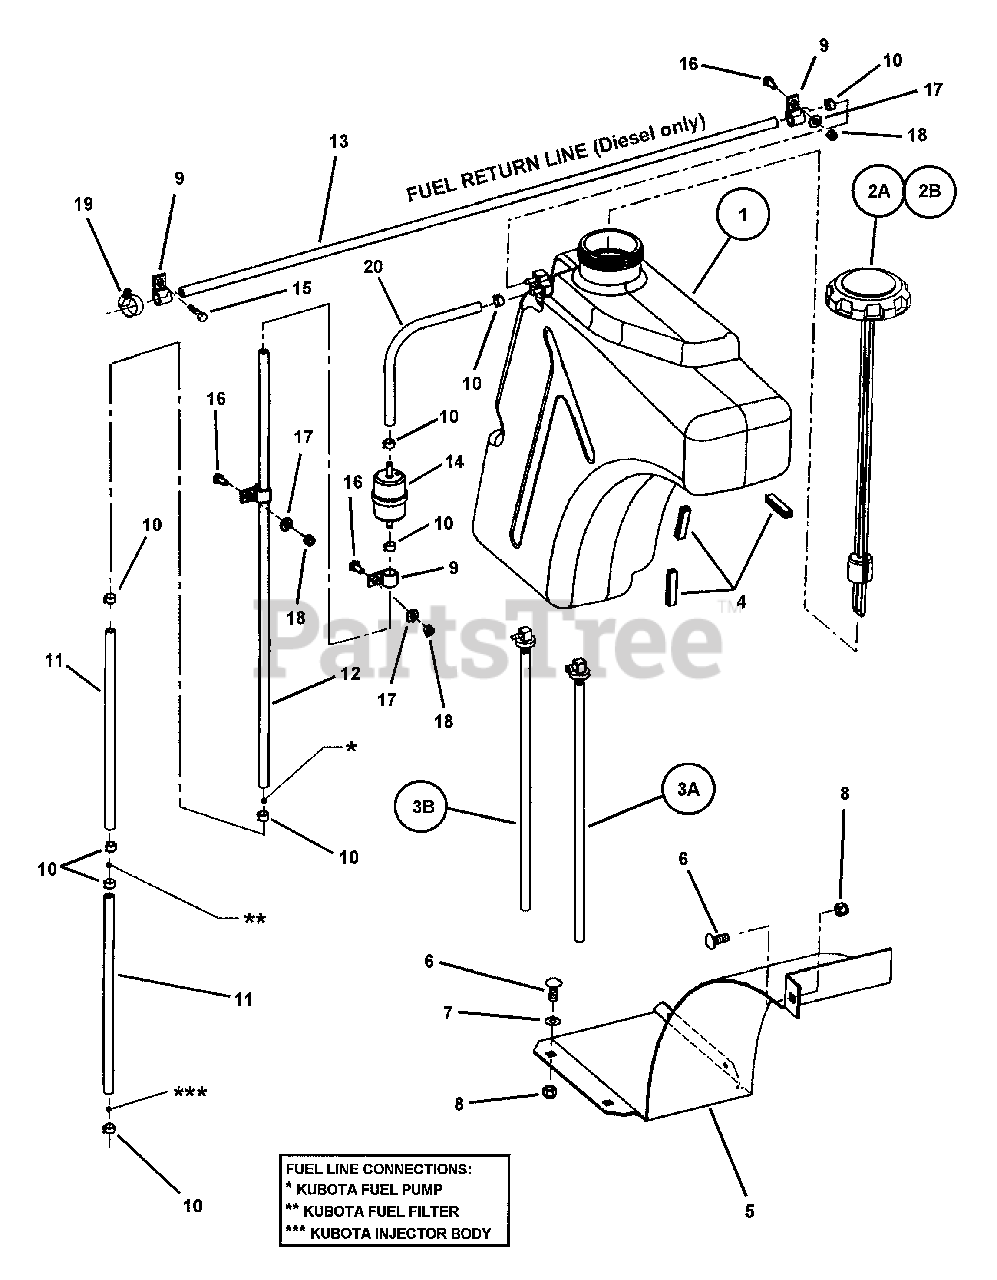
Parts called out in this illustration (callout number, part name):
1	TANK, Fuel
2A	ASSEMBLY, Cap/Gauge
2B	ASSEMBLY, Cap/Gauge
3A	ASSEMBLY, 8mm (5/16") Fuel Pickup
3B	ASSEMBLY, 4mm (5/32") Fuel Pickup
4	TRIM, 2 Inch
5	BRACKET, Fuel Tank Support
6	BOLT, Square Neck Carriage, Grade 5
7	RETAINER, 3/8" Bolt
8	NUT, 3/8-16 HEX NYLON LOCK
9	HARNESS CLIP, 3/8"
10	CLAMP, 9/16" Hose
11	HOSE, Fuel (8mm x 12")
12	HOSE, Fuel (8mm x 28")
13	HOSE, Fuel (8mm x 36")
14	FILTER, Fuel, 5/16" Hose
15	SCREW, 5/16-18 x 5/8" Hex Washer Self-Tap
16	SCREW, 1/4-20 x 5/8" Hex Head Cap, Grade 5
17	WASHER, 1/4" Flat
18	NUT, 1/4-20 HEX NYLON LOCK
19	CLAMP, Hose
20	HOSE, Fuel (6-1/2")
